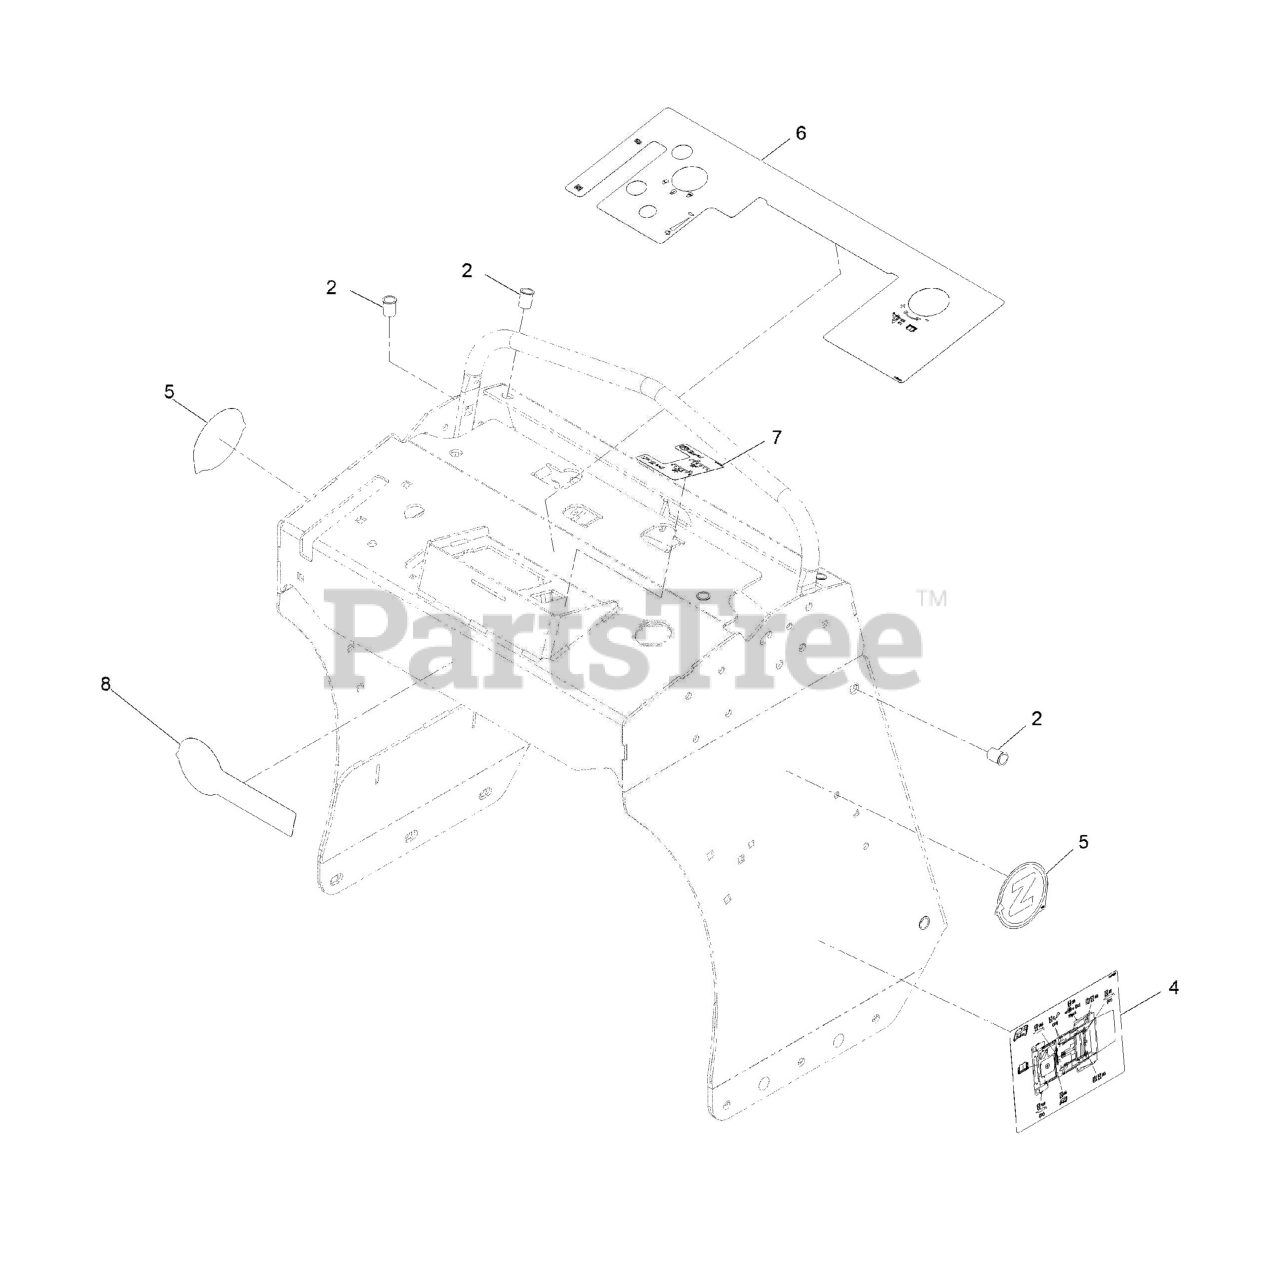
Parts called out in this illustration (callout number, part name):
2	NUT-CLINCH
4	DECAL-AID, SERVICE
5	Decal-Z-Logo
6	DECAL-PANEL, CONTROL
7	DECAL-CONTROL, TINE
8	DECAL-Z-AERATE 24 LOGO
